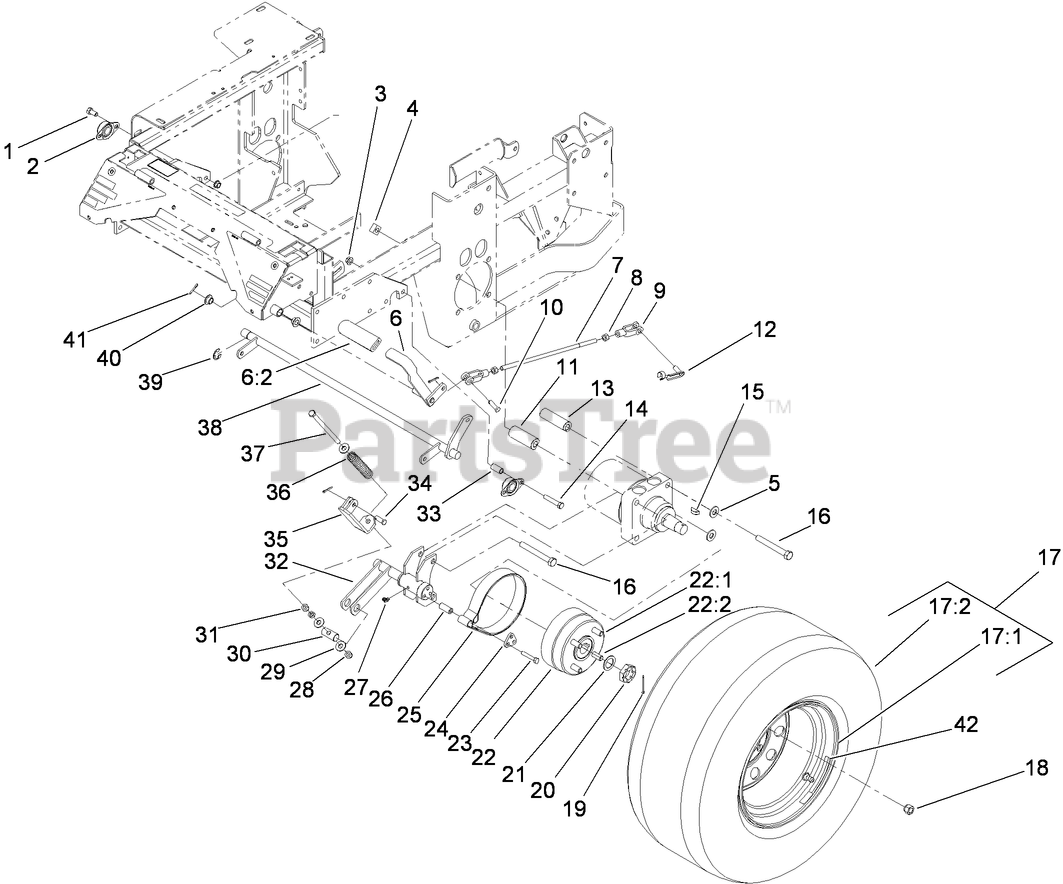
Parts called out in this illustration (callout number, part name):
1	SCREW-HH
2	BEARING-FLANGE, SIDE
3	NUT-HHF, WHIZ
4	NUT-SQUARE, SPECIAL
5	WASHER-THRUST
6	BRAKE LEVER AND GRIP ASM
6:2	GRIP-LEVER
7	ROD-BRAKE
8	NUT-HEX
9	YOKE-LINKAGE, BRAKE
10	PIN-CLEVIS
11	SPACER-WHEEL, SHORT
12	Pin-Spring, Clevis
13	SPACER-WHEEL, LONG
14	SCREW-HH
15	KEY-WOODRUFF
16	SCREW-HH
17	WHEEL AND TIRE ASM
18	NUT-LUG
19	PIN-COTTER
20	NUT-HH
21	WASHER-SPACER
22	WHEEL HUB ASM
22:1	HUB-WHEEL
22:2	STUD-WHEEL
23	SCREW-HH
24	RETAINER-BAND, BRAKE
25	BAND-BRAKE
26	SPACER
27	FITTING-GREASE
28	NUT-LOCK, NI
29	WASHER-FLAT
30	PIN-TRUNION
31	NUT-JAM
32	BRAKE-WIDE
33	SPACER-RETAINER, BRAKE
34	PIN-CLEVIS
35	LINKAGE-BRAKE, LOWER
36	SPRING-BRAKE
37	BOLT-TAP, HH
38	SHAFT-BRAKE
39	E-RING
40	BEARING-CONTROL
41	PIN-COTTER
42	DECAL
